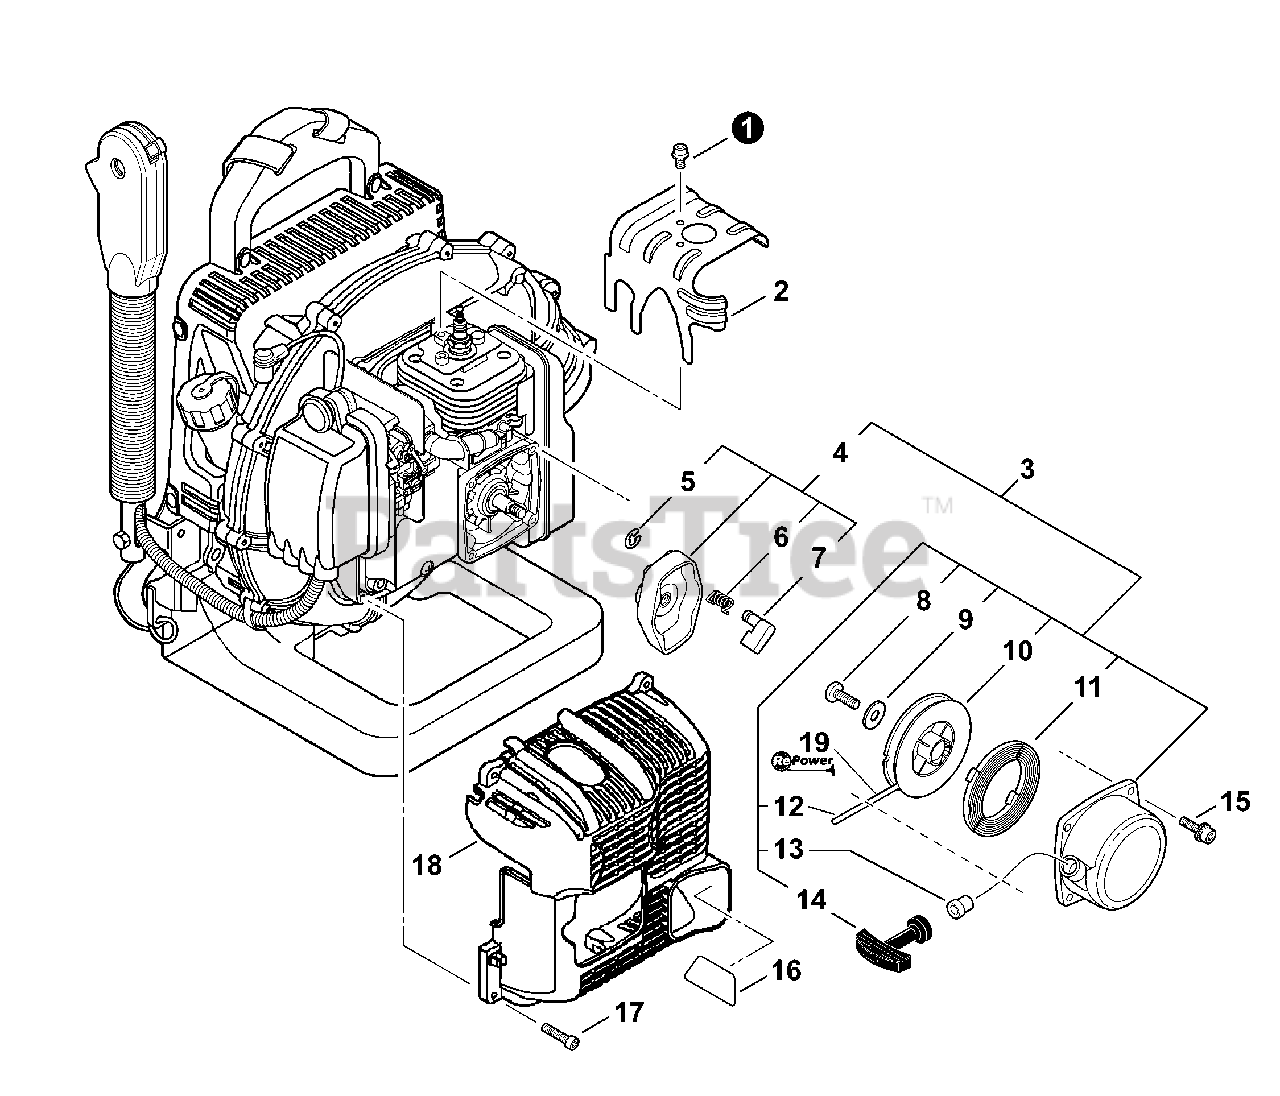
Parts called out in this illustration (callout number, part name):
1	SCREW - 5×8
2	SHIELD, CYLINDER
3	STARTER ASSY
4	STARTER PAWL ASSY
5	RING, RETAINING - 4
6	SPRING, RETURN
7	PAWL, STARTER
10	REEL, ROPE
11	SPRING, REWIND
12	ROPE, STARTER - 4×1110
13	GUIDE, ROPE
14	GRIP, STARTER
15	SCREW - 5×18
16	DEFLECTOR, HEAT
17	SCREW - 5×20 -- TAPPING
18	COVER, ENGINE
19	ROPE, STARTER - REPOWER BULK
